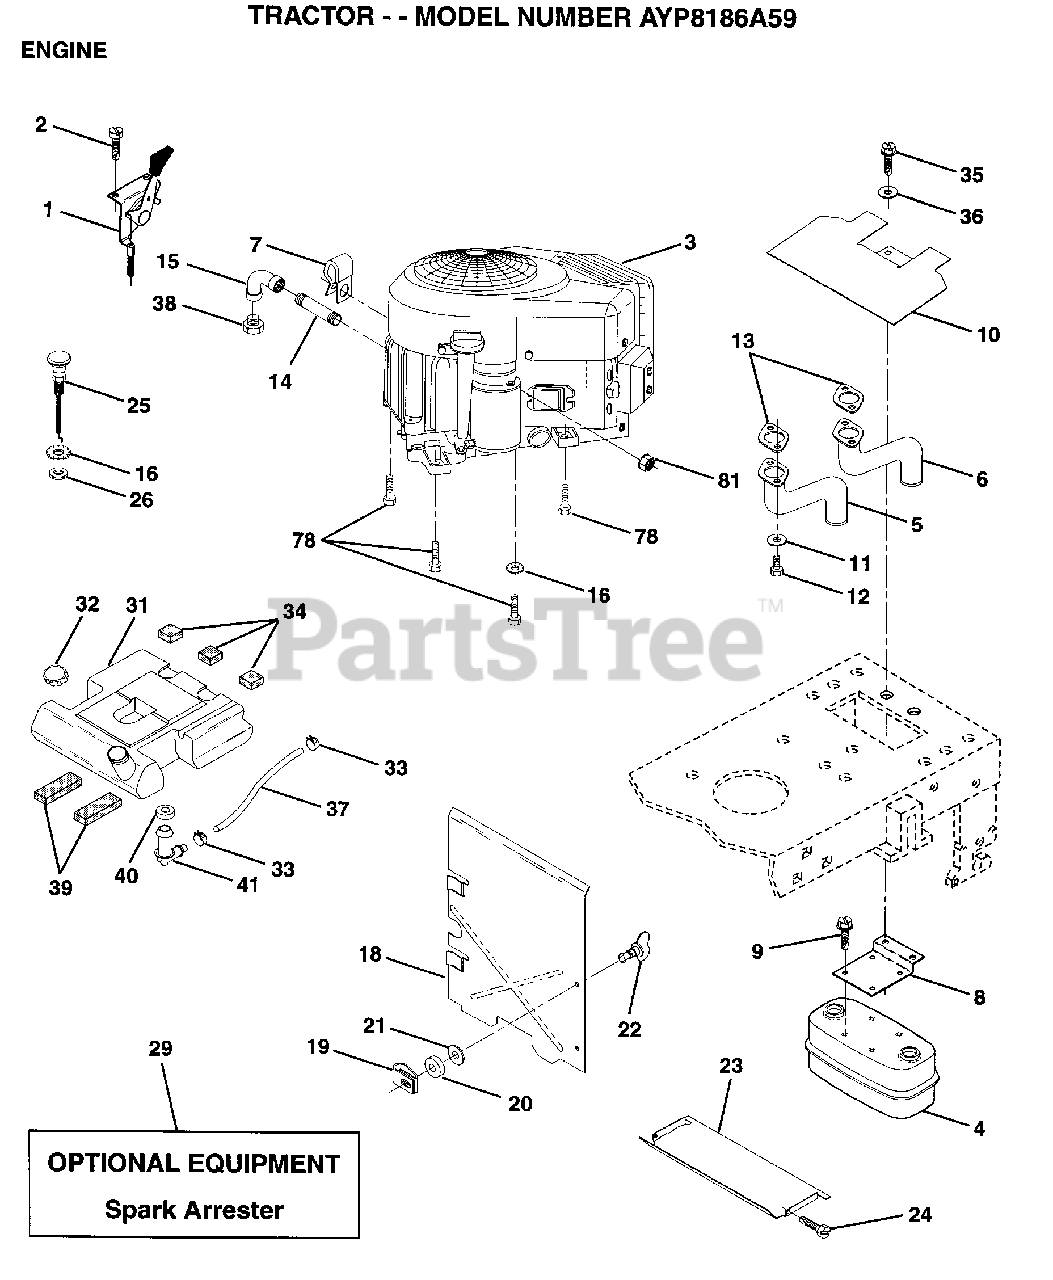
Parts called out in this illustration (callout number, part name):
2	SCREW LT
5	TUBE ASSY EXH LH
6	TUBE ASSY EXH RH
7	CLIP T
8	BRACKET MUFFLER
9	SCREW ST
10	SHIELD.HEAT.
14	PIPE NIPPLE LT
15	ELBOW
16	LOCKWASHER
18	HEAT SHIELD
19	RECEPTACLE LT
20	RETAINER LT
22	STUD.1/4.TURN
23	HEAT SHIELD
24	SCREW
25	CHOKE CONTROL
32	CAP ASM FUEL
33	HOSE CLAMP
34	PAD-SPACER LT
35	SCREW
36	WASHER
37	FUEL LINE T
39	PAD IDLER TI
40	BUSHING OUTLET T
41	STEM.TANK.FUEL
78	SCREW
81	NUT
